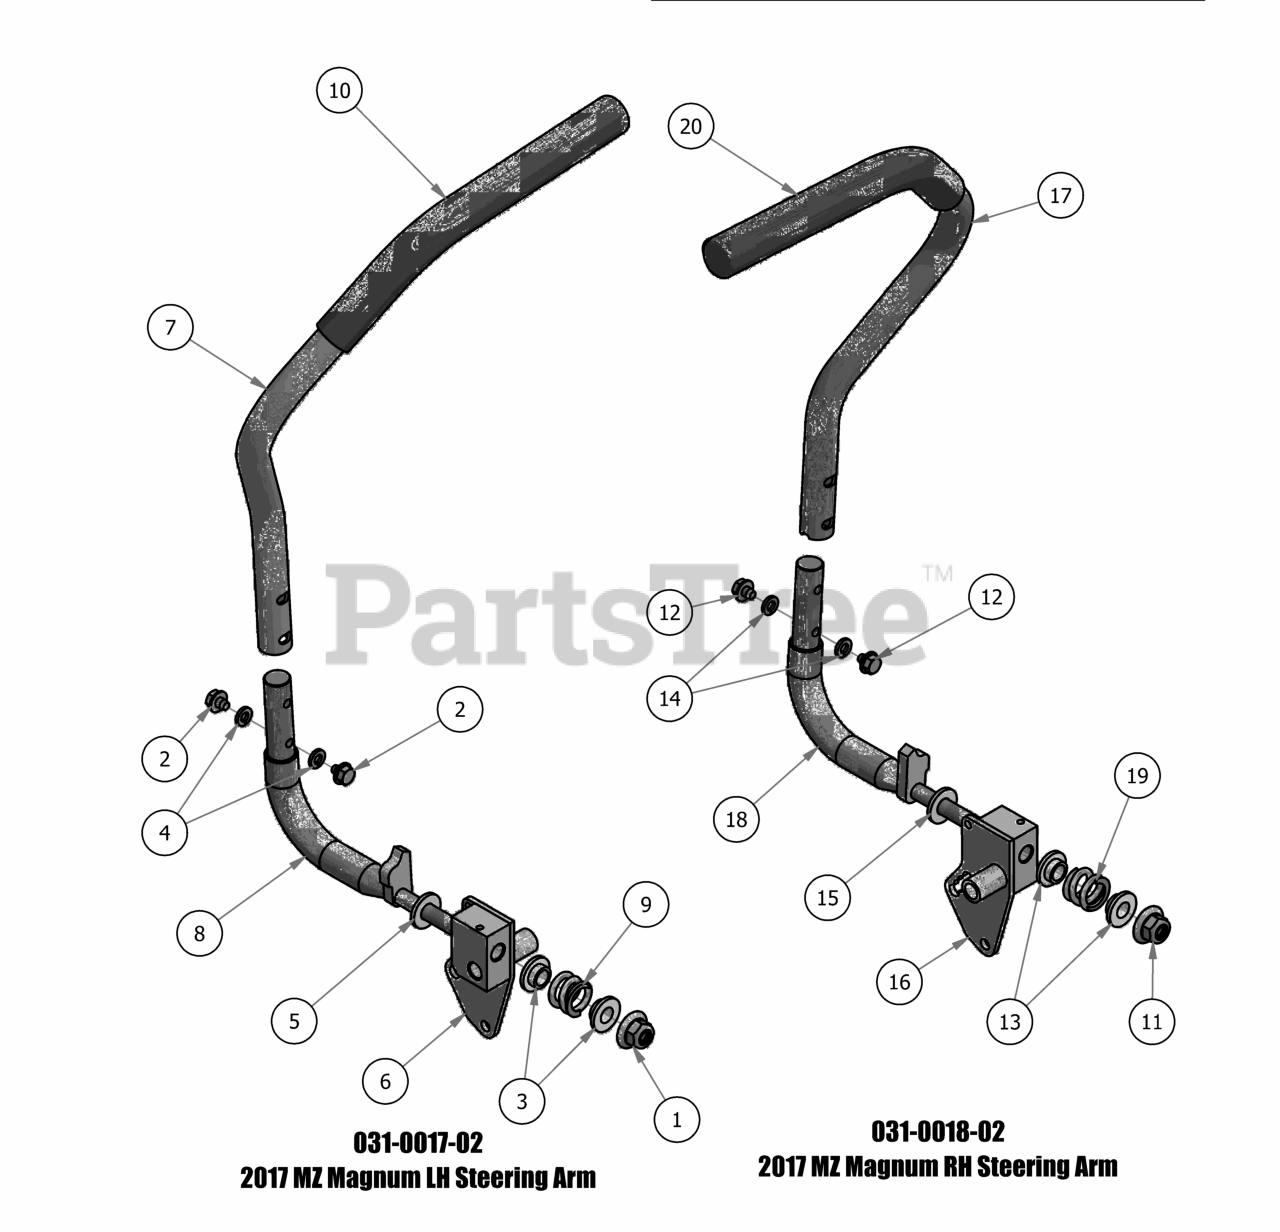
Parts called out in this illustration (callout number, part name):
1	1/2-13 Nylon Flange Nut
2	5/16-18 1/2 HWH Bolt-Steering
3	.515 ID Nylon Shoulder Washer
4	5/16" Lock Washer
5	.505 Nylon Spacer
6	2017 Drive Lever Housing - Left
7	ZT Direction Steering Arm (Left)
8	Steering Arm Elbow - Left
9	Drive Lever Spring
10	Rubber Grip
11	1/2-13 Nylon Flange Nut
12	5/16-18 1/2 HWH Bolt-Steering
13	.515 ID Nylon Shoulder Washer
14	5/16" Lock Washer
15	.505 Nylon Spacer
16	2017 Drive Lever Housing - Right
17	ZT Direction Steering Arm (Right)
18	Steering Arm Elbow - Right
19	Drive Lever Spring
20	Rubber Grip
